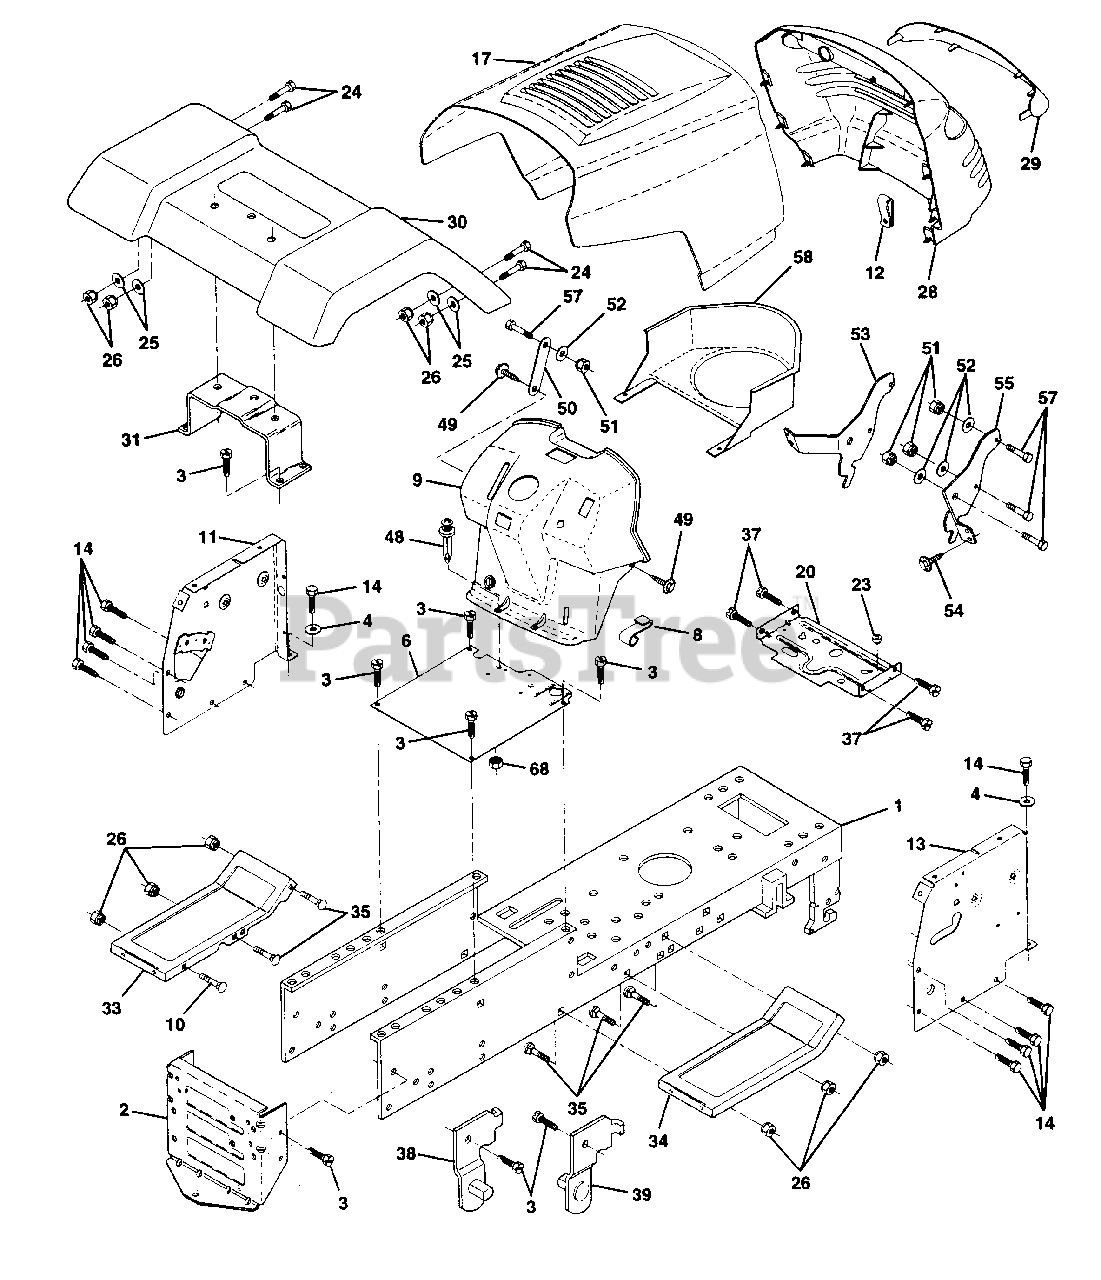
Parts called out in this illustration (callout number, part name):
1	Chassis Weldment 11ga
2	Drawbar, Stretch
3	Screw Thdrol 3/8-16x3/4 Ty-tt
4	Washer 13/32 x 3/4 x 16 Ga.
5	Washer Lock Ext. Tooth 3/8
6	Saddle LT Fender Shift
8	Clip Insulator .406
9	Dash Private Label
10	Bolt Carriage 3/8-16 x 1
11	Panel Pnt Dash Lh
12	Clip Tinnerman Grille P/L
13	Panel Dash Rh Weldment
14	Screw Thdrol 3/8-16x1/2 Ty-tt
17	Hood Paint Steel Private Label
20	Plate Mtg
24	Bolt Fin Hex 3/8-16unc X 1 Gr. 5
25	Washer 13/32 X 13/16 X 12 Ga
26	Nut Lock Hex W/Ins 3/8-16 Unc
28	Grille Private Label
29	Lens Grille Private Label
31	Bracket Pnt Fender
33	Footrest Pnt Lh
34	Footrest Pnt Rh
35	Bolt Rdhd Sht Sqnk 3/8-16 X3/4
37	Screw Thdrol 5/16-18 X3/4
38	Bracket, Asm. Pivot, L.H., Mower Rear
39	Bracket, Asm. Pivot, R.H., Mower Rear
48	Rivet Push Plate D Plastic Blk.
49	Screw Hexwsh. Thdrol 1/4-20 x 3/4
50	Brace
51	Nut Lock Hex W/Ins 1/4-20
52	Washer 9/32 x 7/8 x 16 Ga.
53	Bracket Grille LH
54	Screw Lock Spider #8 x 7/8
55	Bracket, Grille RH
57	Screw Hex 1/4-20 x 3/4
58	Air Duct P/L
68	Nut Keps Hex 1/4-20 UNC
